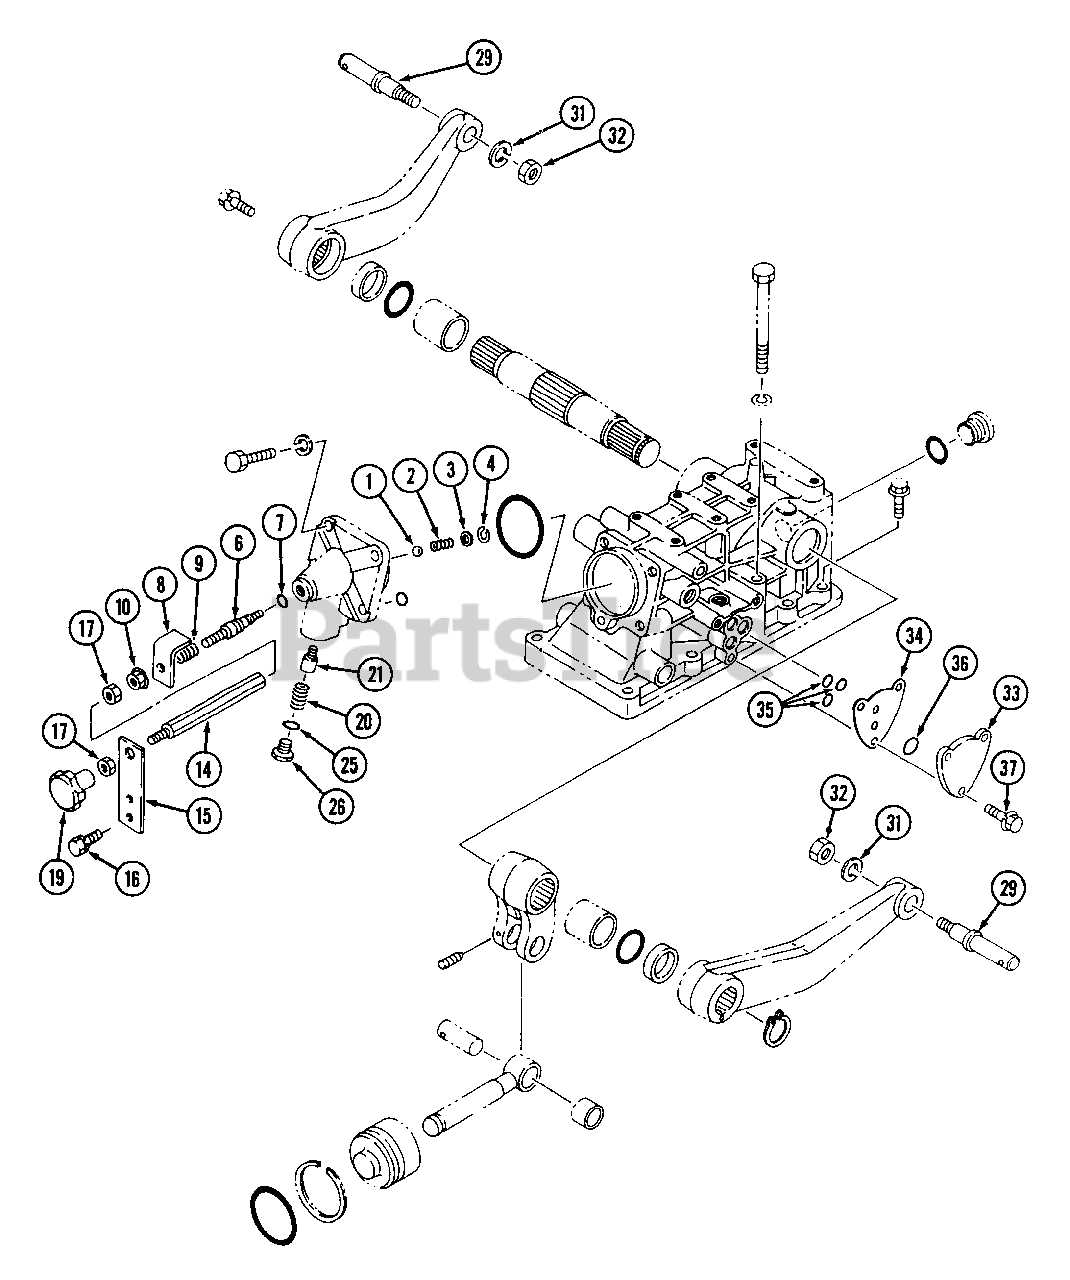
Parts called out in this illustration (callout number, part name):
8	Lever, Stopper
16	Bolt w/Washer
29	Pin, Lift Arm
37	Bolt w/Washer
